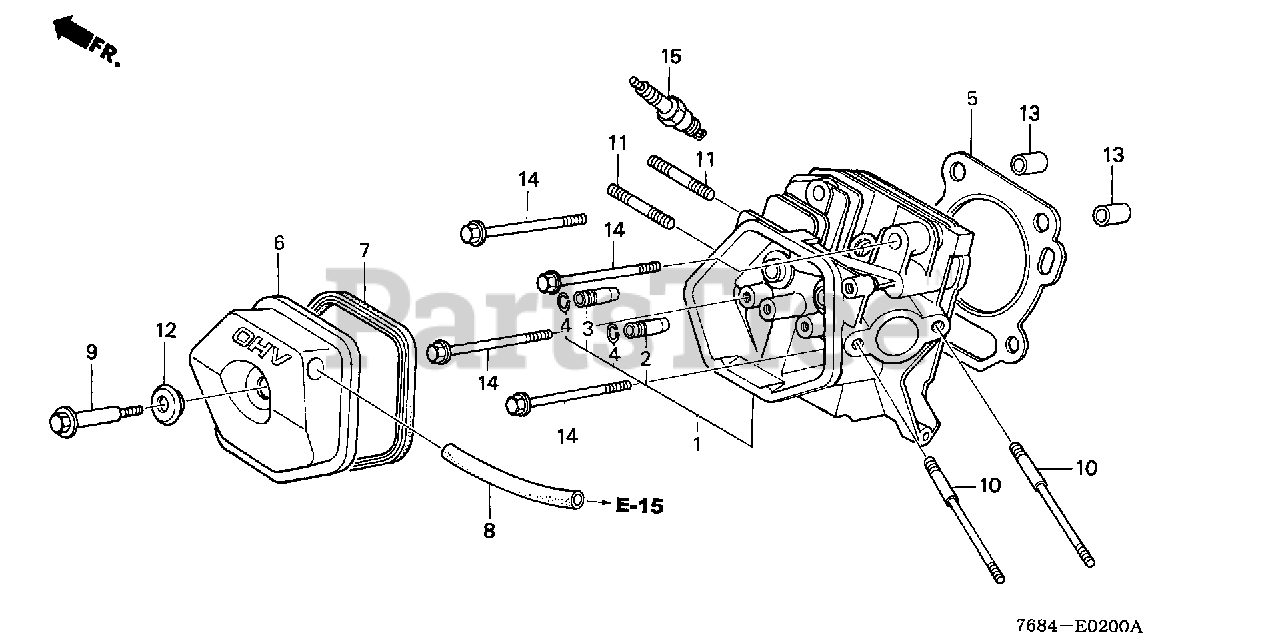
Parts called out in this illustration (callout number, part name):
1	CYLINDER HEAD
2	GUIDE, VALVE (OVER SIZE)
3	GUIDE, EX. VALVE (OVER SIZE)
4	CLIP, VALVE GUIDE
5	GASKET, CYLINDER HEAD
6	COVER, HEAD
7	GASKET, HEAD COVER
8	TUBE, BREATHER
9	BOLT, HEAD COVER
10	BOLT, STUD (8X123)
11	BOLT, STUD (8X32)
12	WASHER, HEAD COVER
13	PIN, DOWEL (12X20)
14	BOLT, FLANGE (10X80)
15	SPARK PLUG (BPR5ES) (NGK)
15	SPARK PLUG (W16EPR-U) (DENSO)
